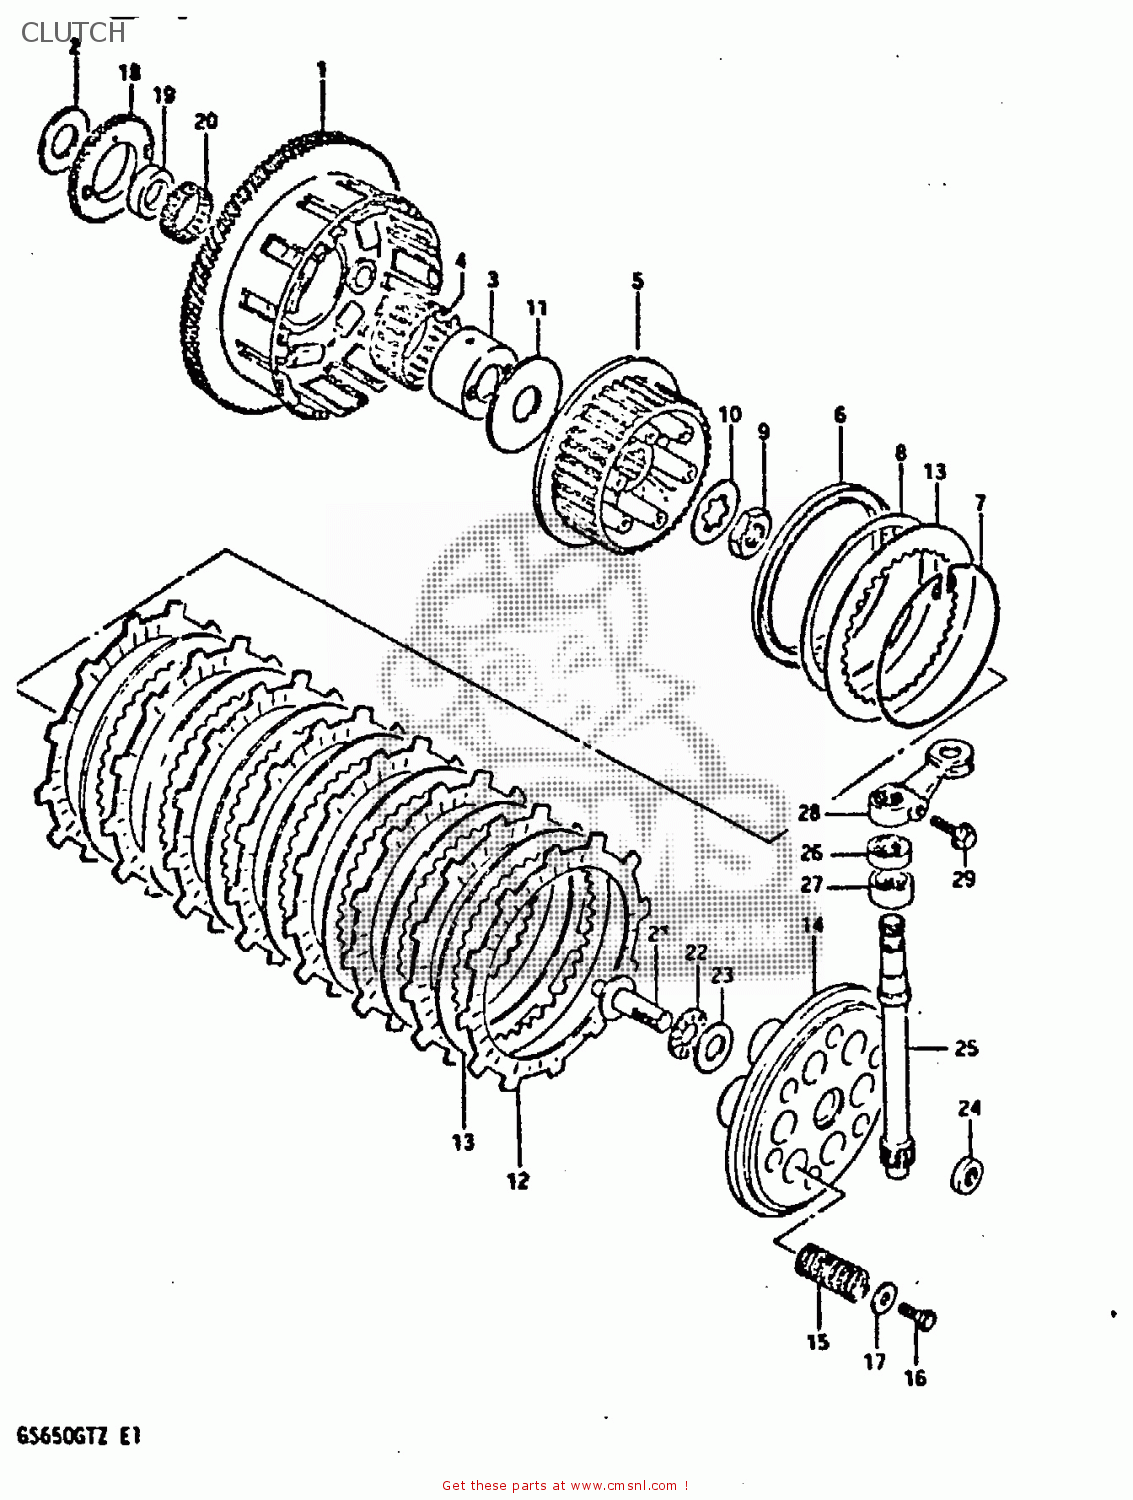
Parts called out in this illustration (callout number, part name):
1	GEAR ASSEMBLY,PRIMARY DRIVE
2	WASHER
3	SPACER
4	BEARING
5	HUB,CLUTCH SLEEVE
6	SEAT,WAVE WASHER
7	RING,STOPPER
8	WASHER
9	NUT
10	WASHER,LOCK
11	WASHER(25X66X3.5)
12	PLATE,CLUTCH DRIVE (MCA)
13	PLATE,CLUTCH DRIVEN(T:2.0) (NAS)
14	DISC,CLUTCH PRESSURE
15	SPRING
16	BOLT, UPPER
17	WASHER
18	GEAR,OIL PUMP DRIVE
19	SPACER,OIL PUMP DRIVE GEAR
20	BEARING(36X40X10)
21	RACK,CLUTCH RELEASE
22	BEARING(15X28X2)
23	WASHER
24	SEAL,OIL(10X16X5)
25	PINION,CLUTCH RELEASE
26	OIL SEAL
27	BEARING(15X22X12)
28	ARM,CLUTCH RELEASE
29	BOLT,REAR
